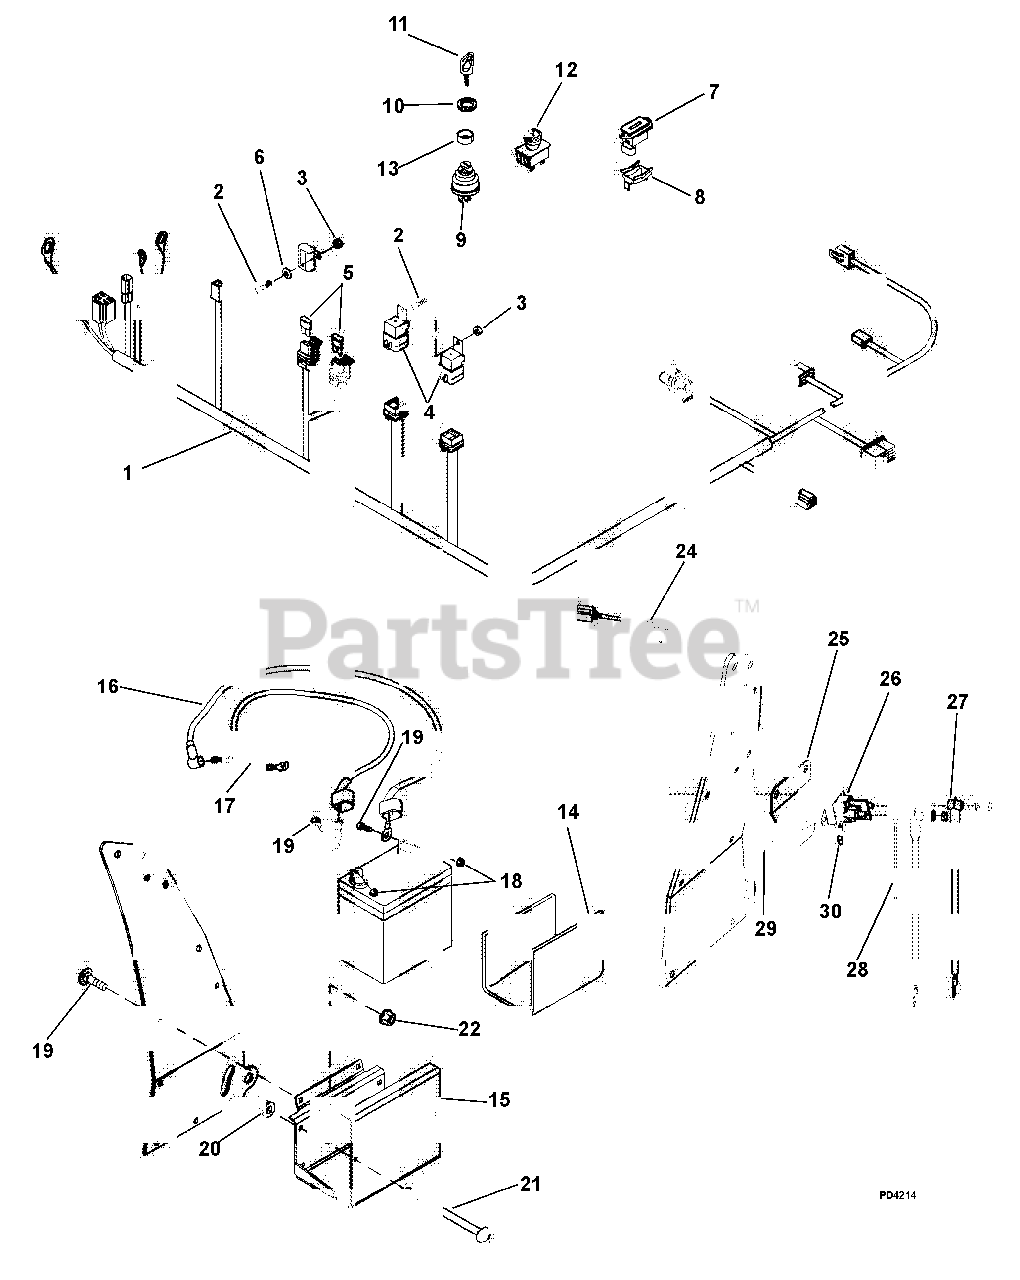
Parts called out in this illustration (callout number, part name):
1	Wiring Harness, Main
2	Bolt, Hex M5-.8 x 16
3	Nut, Hex M5 x .8
4	Relay, Sealed With Bracket
5	Fuse, 20 Amp
6	Washer, Flat Steel .219 x .50 x .049
7	Meter, Hour - LCD
9	Key Switch
10	Nut, Knurled
11	Ignition Key
12	Switch, PTO
14	Isolator Pad, Battery
15	Battery Box
16	Cable, Positive
17	Cable, Negative
18	Nut, Lock, Nylon M8-1.25
19	Bolt, Round Head Square Neck M8-1.25 x 20
20	Nut .31-18 Nyloc Flange
21	Cap Screw 5/16" x 6"
22	Nut, Lock, Nylon M8-1.25
23	Battery
24	Adapter Assembly, Kawasaki
25	Solenoid Mounting Plate
26	Solenoid
27	Starter Cable
28	Fusible Link, 20 Amp
29	Bolt, Hex .25-20 x .75
30	Nut, Locking, Flange .250-20
